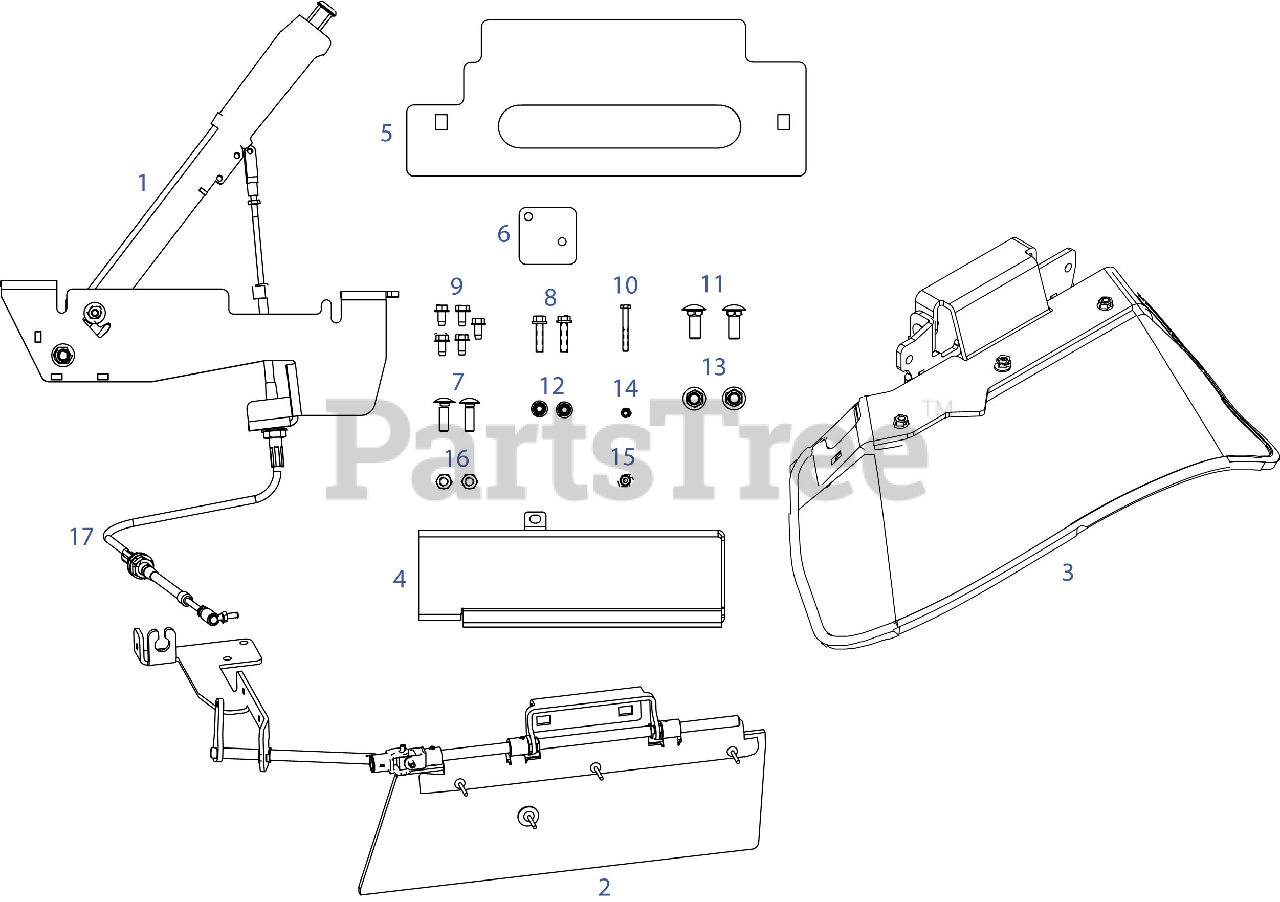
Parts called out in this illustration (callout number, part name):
1	Door Handle Group
2	Chute Door Group (54?/60? Deck)
2	Blade Restrictor Flap
3	Chute Assembly (54?/60? Deck)
6	Cable Bracket Spacer
7	Carriage Bolt, 5/16-18 x 1.00
8	Hex Cap Screw, 1/4-20 x 1.00
9	Self tapping Screw, 1/4-20 x .500
10	Screw, #10-24 x 1.625
11	Carriage Bolt, 3/8-16 x 1.00
12	Nut, 1/4-20, Flangelock
13	Nut, 3/8-16, Flangelock
14	Nut, #10-24, Hex
15	Nut, #10-32, Nylock
16	Nut, 5/16-18, Hexlock
17	Control Cable
